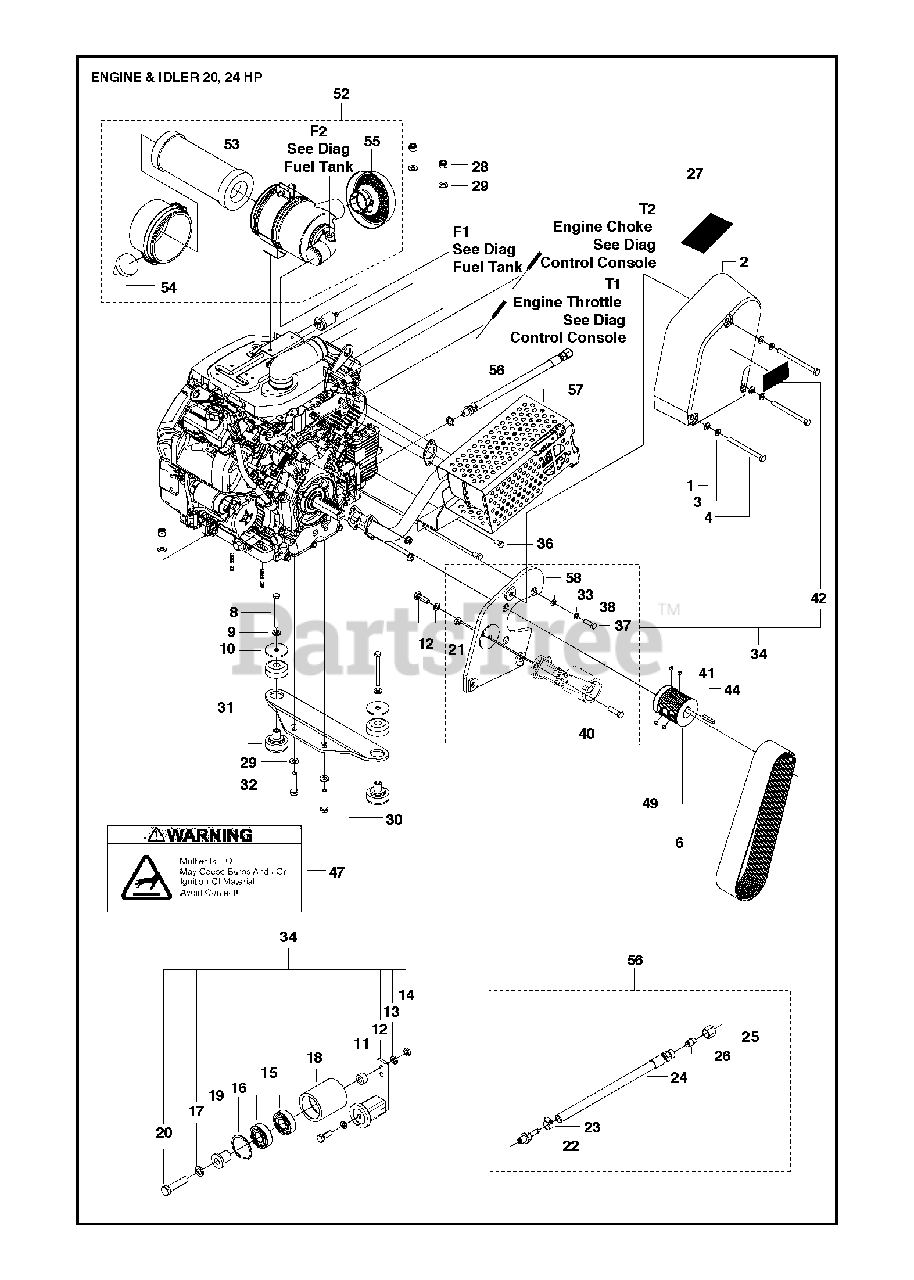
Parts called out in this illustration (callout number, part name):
1	WASHER
3	SPRING WASHER
17	WASHER
21	HEXAGON LOCKING NUT
23	CLAMP, HOSE, MAH-4 FUEL LINE
28	HEXAGON LOCKING NUT
29	WASHER
33	WASHER
36	SCREW EHHM
38	SPRING WASHER
53	ANTIVIBRATION ELEMENT
